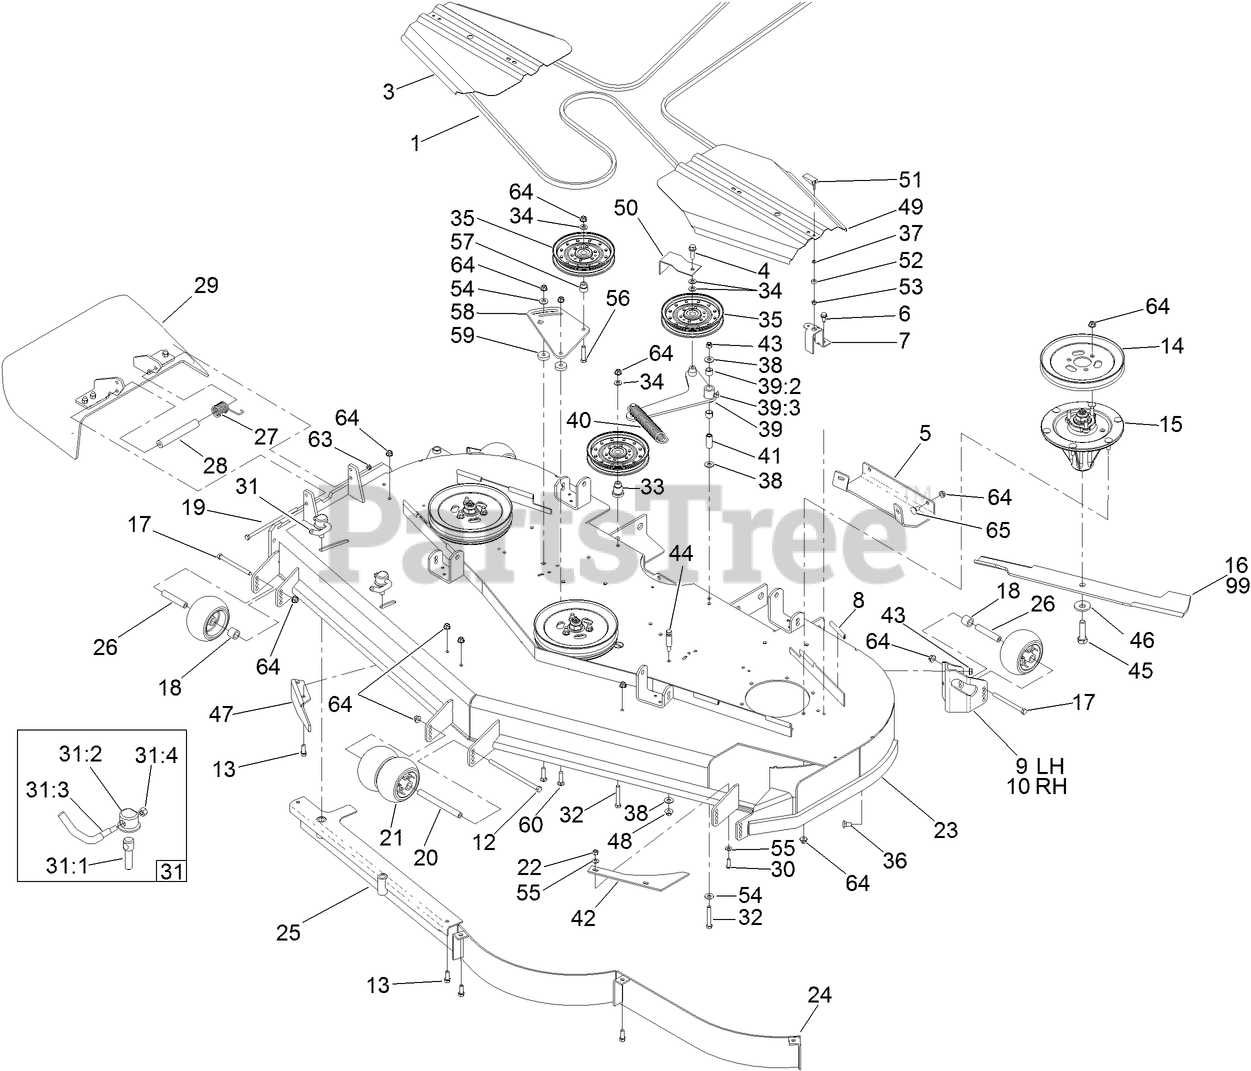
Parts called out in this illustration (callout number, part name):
3	COVER-BELT, RH
4	SCREW-HHF
5	PLATE-SKID
6	SCREW-HWHTF
7	BRACKET-COVER
8	STRIP-SEAL
9	MOUNT-WHEEL, LH
10	MOUNT-WHEEL, RH
12	SCREW-HH
14	PULLEY
15	SPINDLE ASM
16	BLADE-HI FLOW, 24.5 INCH
17	SCREW-HH
18	TUBE-SPACER
19	SCREW-HH
20	SPACER-WHEEL
21	ROLLER-SCALP, ANTI
22	NUT-LOCK, NI
23	DECK DECAL ASM
26	TUBE-SPANNER
27	SPRING-TORSION
28	SPACER
29	RUBBER DEFLECTOR ASM
30	SCREW-HSBH
31	LEVER ASM
31:1	SCREW-LOCK
31:2	CAP-LOCK
31:4	NUT-LOCK, NI
32	SCREW-HH
33	MOUNT-PULLEY
34	WASHER-FLAT
36	SCREW-HH
37	WASHER
38	WASHER-FLAT
39	DECK IDLER ARM ASM
39:2	SLEEVE-BEARING
39:3	FITTING-GREASE, 90 DEG
40	SPRING-EXTENSION
41	BUSHING
42	PLATE-TURBO
44	PIN-THREADED, SPRING ANCHOR
45	SCREW-BLADE
46	WASHER-BLADE BOLT, HEAVY
47	BAFFLE-DISCHARGE
48	NUT-HF
49	COVER-BELT, LH
50	GUIDE-BELT
51	HANDLE-LATCH, SWELL
52	BUSHING-LATCH, SWELL
53	NUT-LOCK, HH
54	WASHER-BELLEVILLE
55	WASHER-SPRING
56	SCREW-HH
57	BUSHING-IDLER
58	PLATE-IDLER
59	SPACER
60	SCREW-HH
63	NUT-LOCK, NI
64	NUT-HF, NI
65	SCREW-CARR
99	BLADE-MID FLOW, 24.5IN
99	BLADE-LO FLOW, 24.5IN
99	BLADE-ATOMIC, 24.5IN
99	BLADE-RECYCLER, 24.5IN
